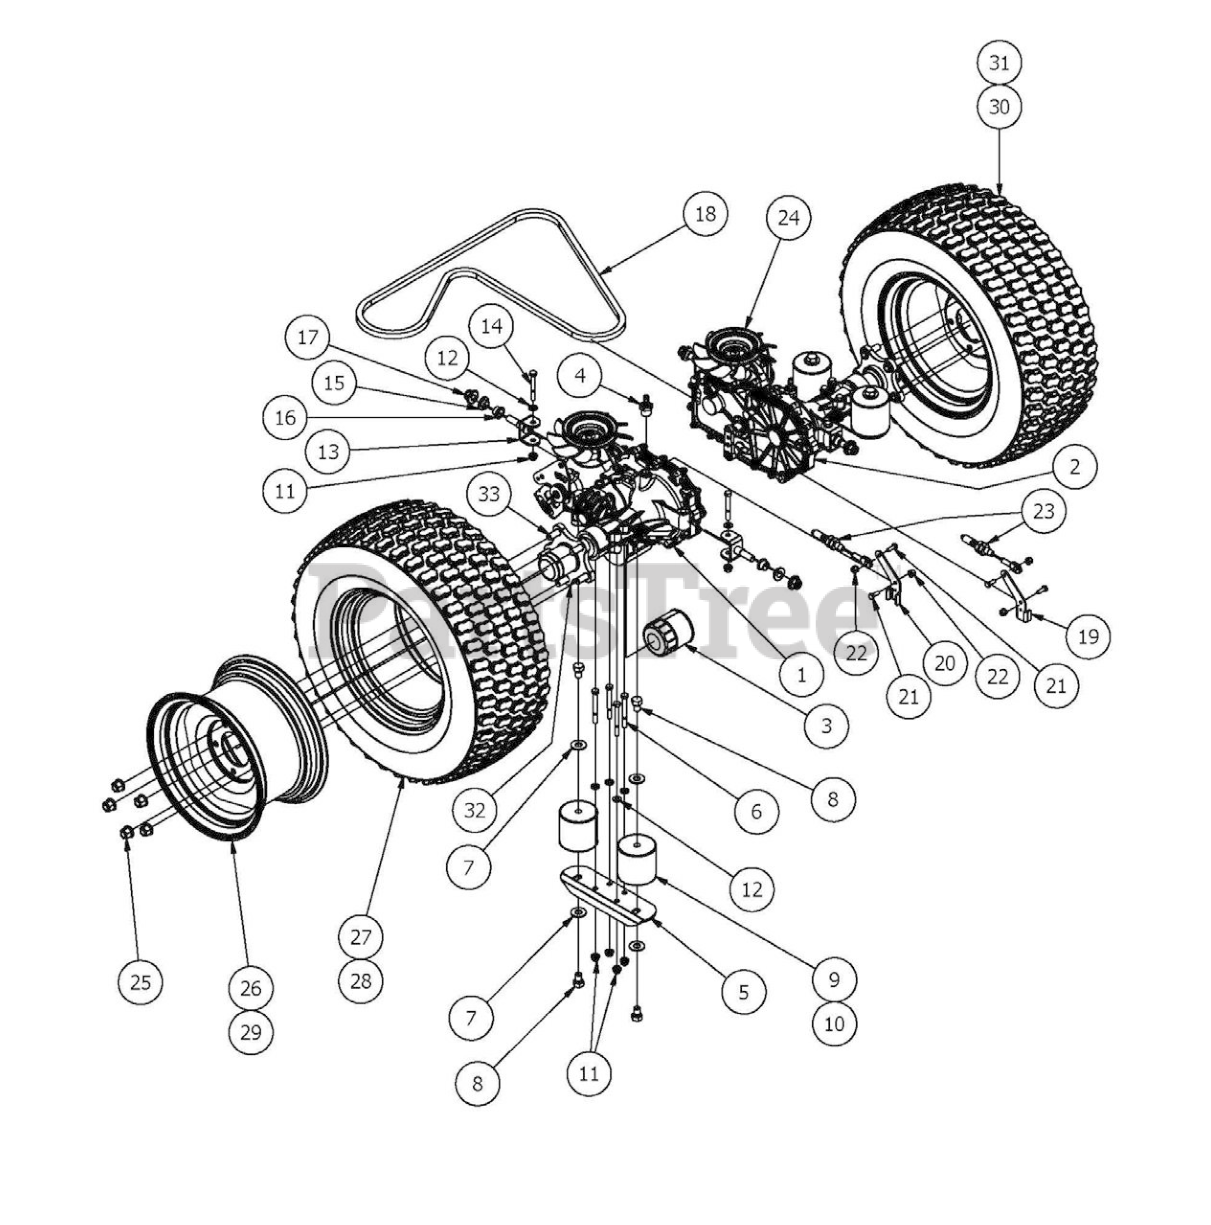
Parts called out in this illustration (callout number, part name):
1	3200 Left transaxle
2	3200 right transaxle
4	45 degree fitting
5	Rear Susp Transaxle Mount
6	5/16" x 3" Hex Bolt
7	1/2" Washer (Grade 8)
8	1/2" x 3/4" Hex Bolt
9	Vibration Mount-Green Dot
10	Vibration Mount-Red Dot (48" Maverick Only)
11	5/16" Flange Nut
12	5/16" Flat Washer
13	Maverick Rear Transaxle Pivot Bracket
14	5/16" x 2 1/2" Bolt
15	.515 ID Nylon Shoulder Washer
16	Bronze Bushing - SF - 2024-8
17	1/2-13 Nylon Flange Nut
18	75.8" Pump Belt
19	Brake Arm Ext (Right)
20	Brake Arm Ext (Left)
21	1/4" x 3/4" Hex Bolt
22	1/4-20 Nylon Insert flange Nut
23	Brake Cable
24	Fan/Pully Kit for ZT and Maverick
25	Acorn Lug Nut
26	12" Black Wheel
27	23 x 10.50 -12 Tire
28	23 x 8.50 12 Tire (48" Maverick Only)
29	12 x 7" Black Wheel (48" Maverick Only)
30	Tire and Wheel Assembly (26 and 27)
31	Tire and Wheel Assembly (28 and 29) (48" Maverick Only)
32	Transaxle Hub
33	Transaxle Wheel Stud
